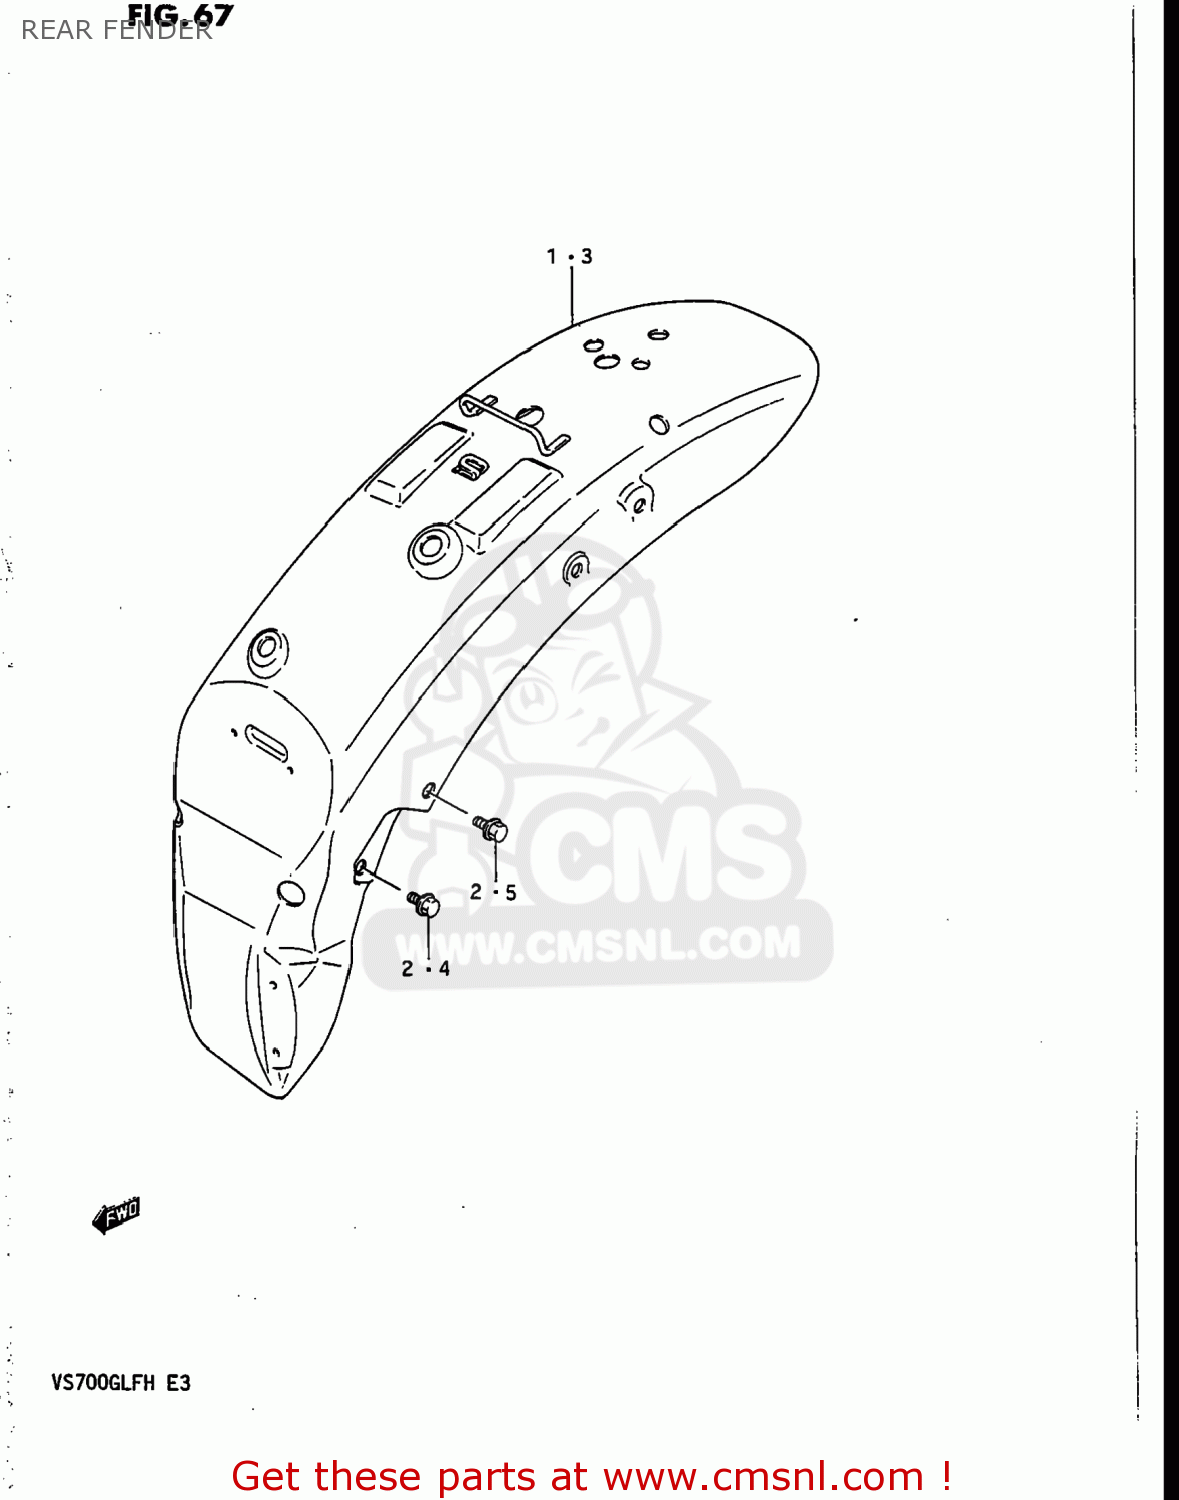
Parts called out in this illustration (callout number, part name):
1	FENDER,REAR
2	BOLT
3	FENDER,REAR
4	BOLT
5	BOLT
